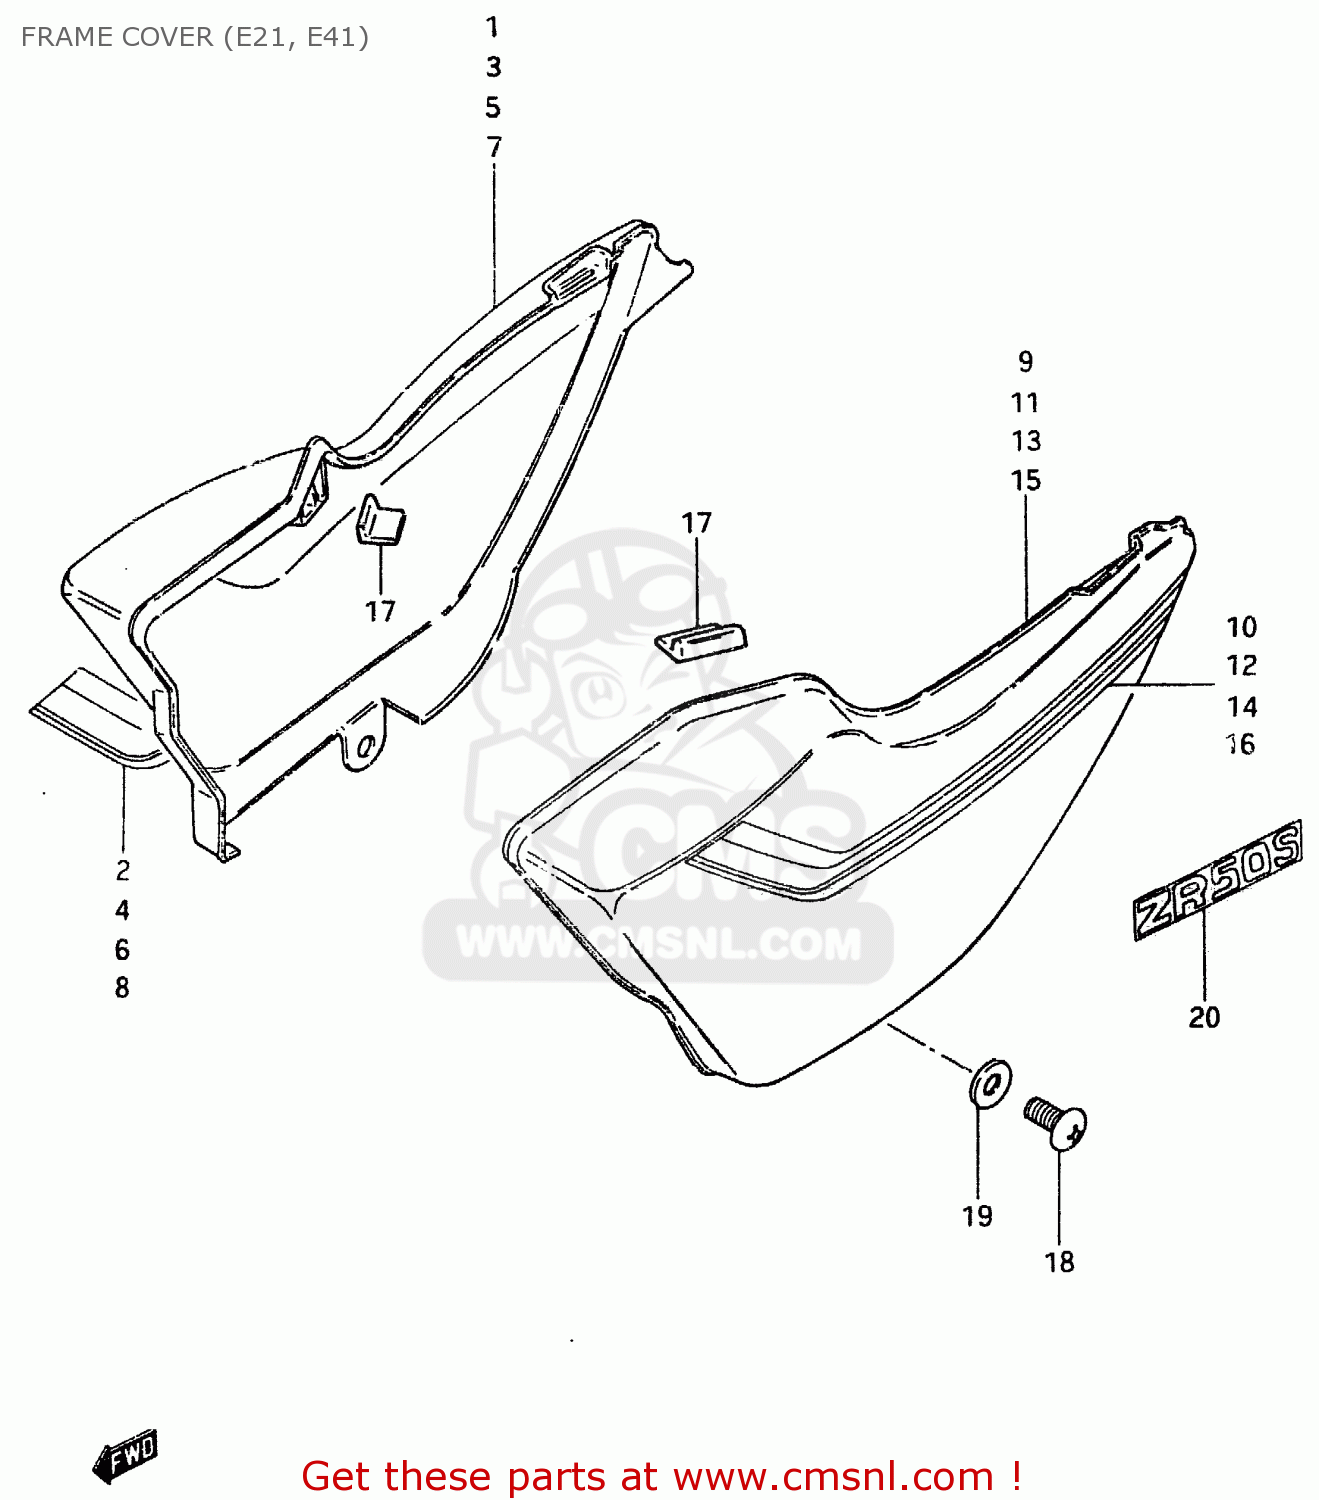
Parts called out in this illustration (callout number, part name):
1	COVER, FRAME RH (BLACK)
2	TAPE, RH
3	COVER, FRAME RH (BLUE)
4	TAPE, RH
5	COVER, FRAME RH (RED)
6	TAPE, RH
7	COVER, FRAME RH (WHITE)
8	TAPE, RH
9	COVER, FRAME LH (BLACK)
10	TAPE, LH
11	COVER, FRAME LH (BLUE)
12	TAPE, LH
13	COVER, FRAME LH (RED)
14	TAPE, LH
15	COVER, FRAME LH (WHITE)
16	TAPE, LH
17	CUSHION,FRAME COVER
18	SCREW
19	WASHER
20	EMBLEM
